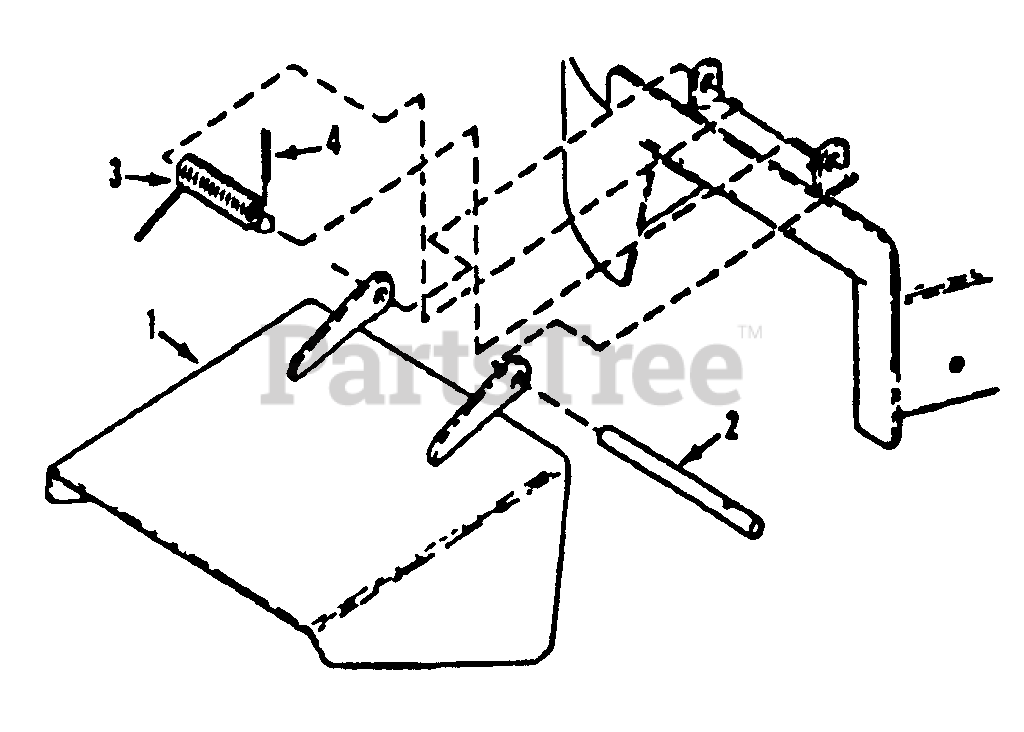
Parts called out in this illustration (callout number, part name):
1	5/8-18 Hexagon Head Nut
2	Spindle
3	Snap Ring
5	Bearing
6	Housing, Cutter
7	Cutter Housing Assembly
9	1/4' Spacer
10	1/2 Spacer
11	Washer. Steel
12	Blade Bolt W/Nut
